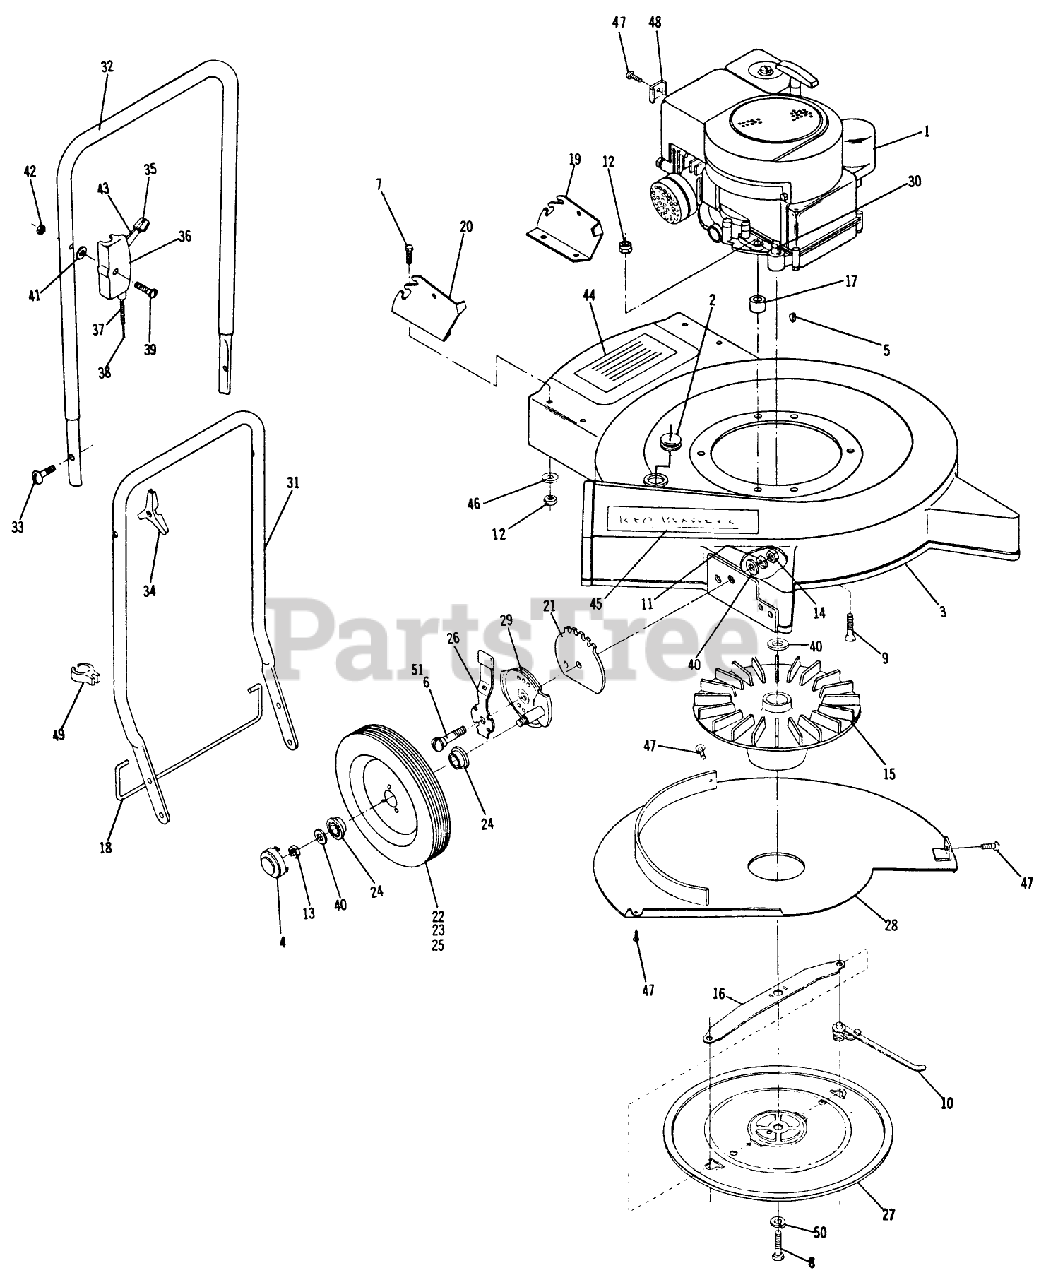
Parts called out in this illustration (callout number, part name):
1	Engine
2	Plastic Plug
3	Deck-Magnesium
4	Hub Cap-Plastic
5	Key #5 Woodruff
6	Bolt, 3/8-16 x 1/2
7	Bolt 5/16-18 x 1
8	Bolt Hex 3/8-24 x 2 1/2
9	Bolt C-Sunk Hd. 5/16-18 x 2
11	Lockwasher
12	Nut-Nylok
15	Fan Wheel
16	Retainer
17	Spacer
18	Bar-Handle
19	Handle Bracket-Left
20	Handle Bracket-Right
21	Index Plate
22	Wheel-Complete
25	Wheel
26	Adjustment Arm
27	Rotor
28	Fan Shield
29	Axle Plate
30	Oil Gauge
32	Handle-Upper
33	Bolt 5/16-18-Special
35	Knob-Plastic
36	Control Deck-Plastic
37	Wire-Housing
39	Screw 1/4-20 x 1 1/4
40	Washer
41	Washer
42	Nut-Nylok
43	Handle
44	NUT, CONDUIT, 1/2 INCH
45	Decal
46	Washer
47	Screw # 10-12 Type-A x 5/8
48	CLIP-CABLE
49	Clip-Control
51	SPACER CLUTCH ARM
